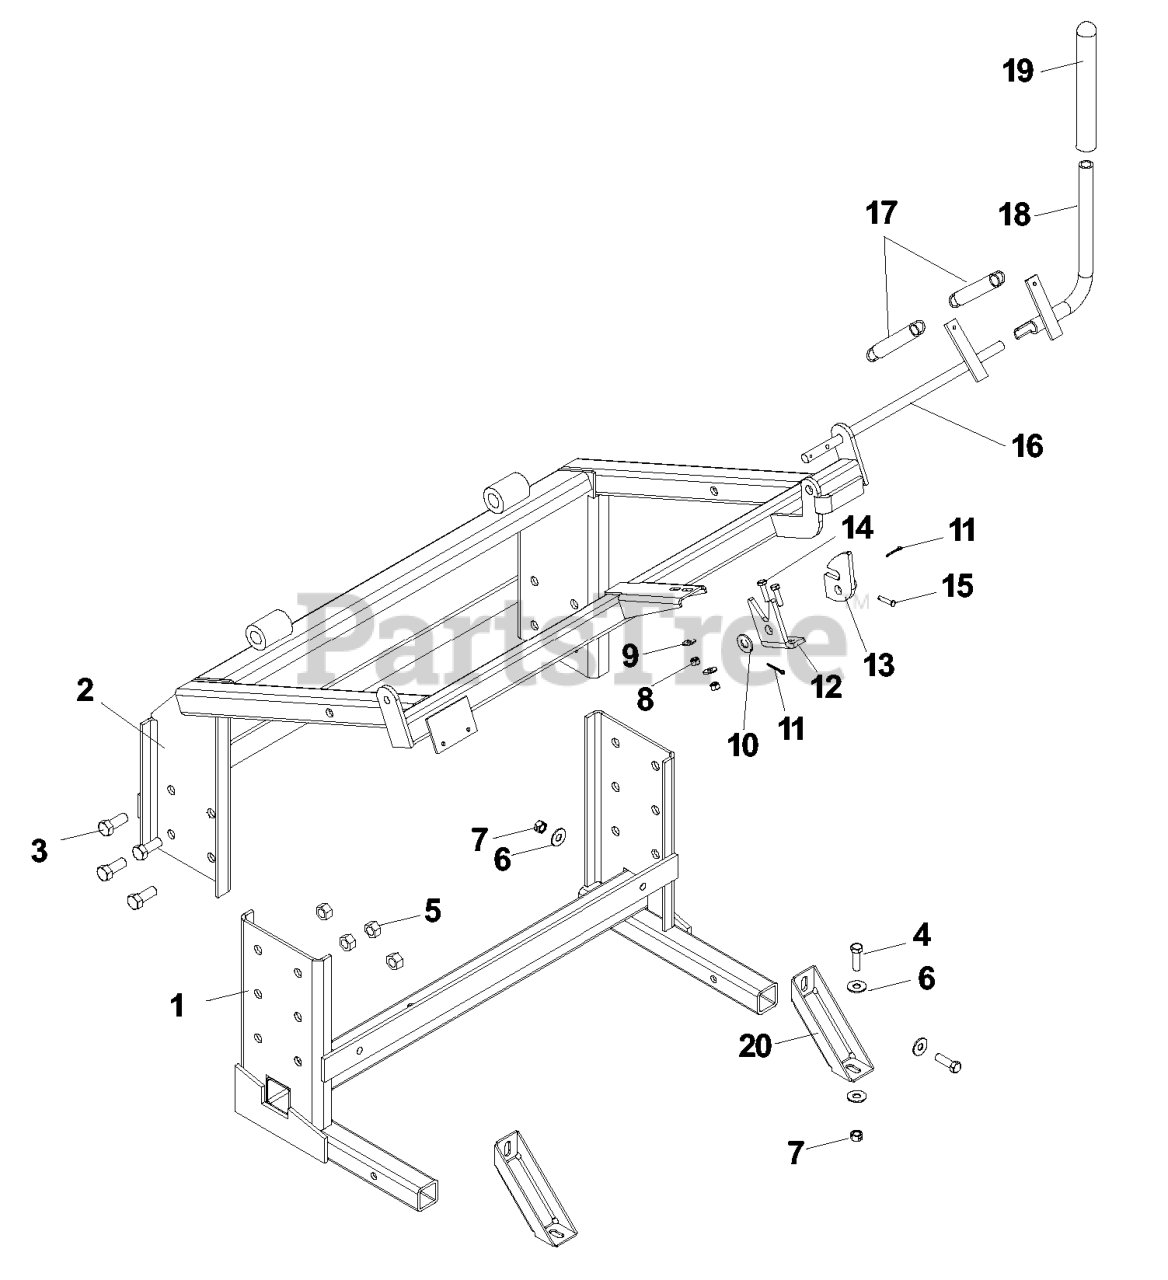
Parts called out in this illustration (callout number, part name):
1	LOWER FRAME
2	UPPER FRAME
3	BOLT 1/2 X 1.25
4	BOLT 3/8 X 1.25
5	NUT 1/2 NYLOC
6	FLAT WASHER 3/8
7	NUT 3/8 NYLOC
8	NUT, 1/4-20, NYLOC
9	WASHER, 1/4
10	FLAT WASHER 1/2"
11	PIN, COTTER, 3/32 X 3/4
12	LATCH BASE
13	WELDMENT, LATCH CATCH BLK
14	BOLT, 1/4-20 X 1
15	PIN, CLEVIS, 3/16 X 1
17	SPRING
18	RELEASE LEVER
19	GRIP
20	HITCH BRACKET
